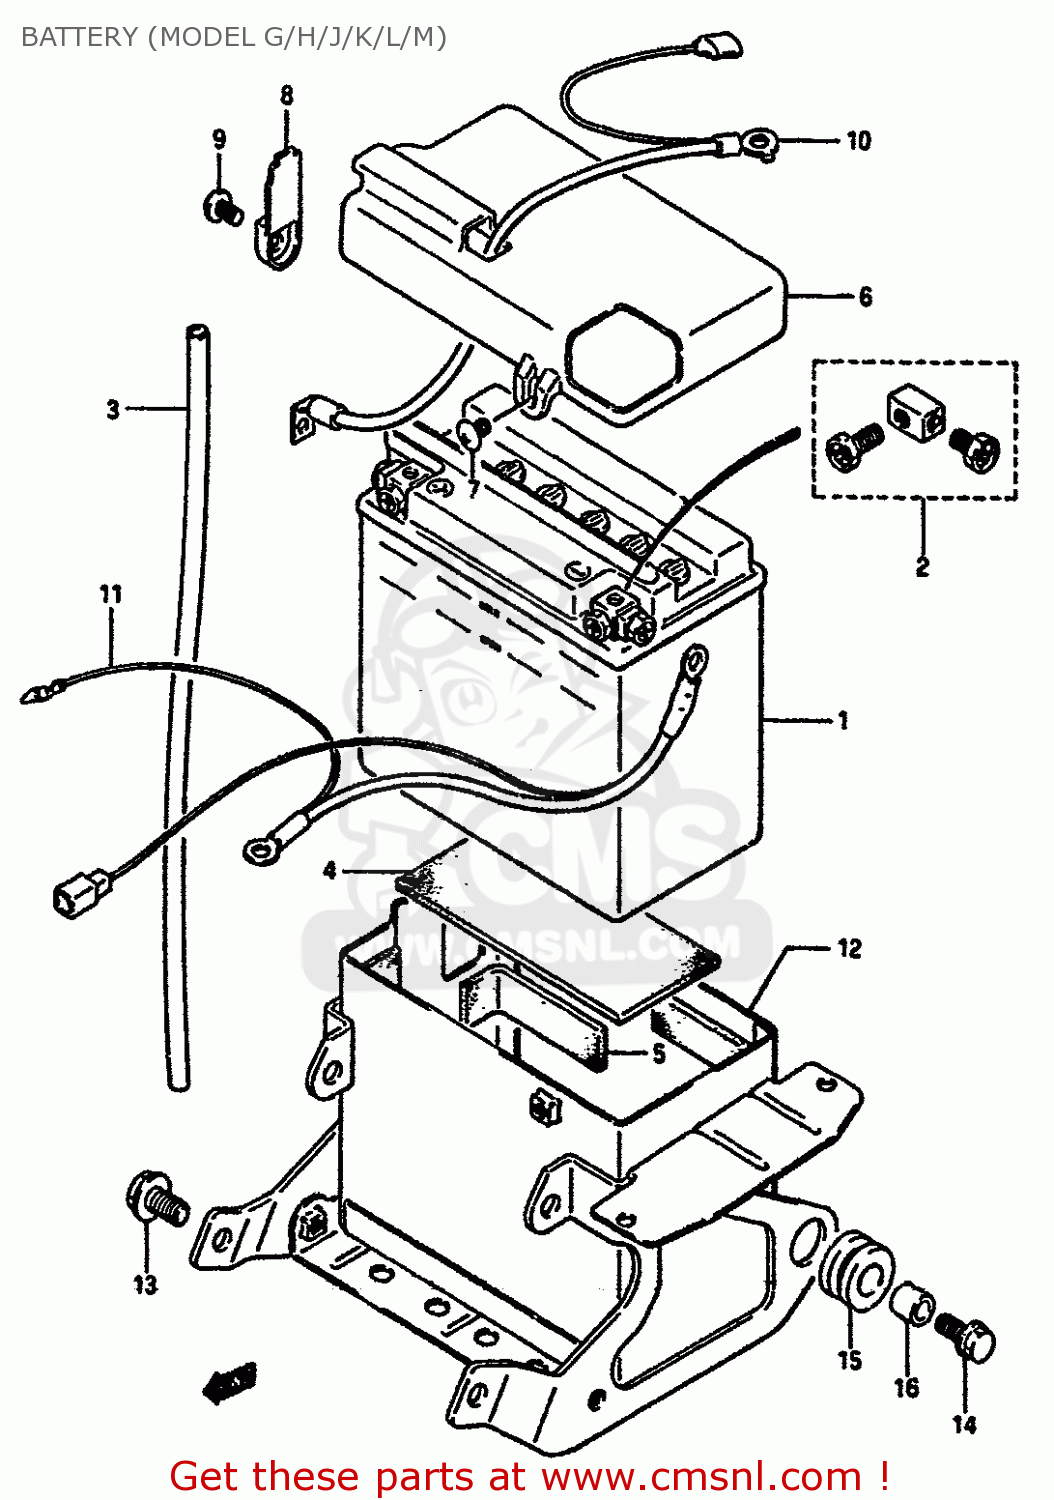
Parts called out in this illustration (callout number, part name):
1	BATTERY ASSY (12V)
2	BOLT SET,BATTERY TERMINAL
3	HOSE,BATTERY EXHAUST
4	PROTECTOR(170X95X3.0)
5	PROTECTOR(20X90)X2
6	COVER,BATTERY UPR
7	SCREW
8	COVER,BATTERY TERMINAL
9	SCREW
10	WIRE,BATTERY PLUS LEAD
11	WIRE,BATTERY MINUS LEAD
12	HOLDER,BATTERY
13	BOLT
14	BOLT
15	CUSHION
16	SPACER (8.8X12X11)
